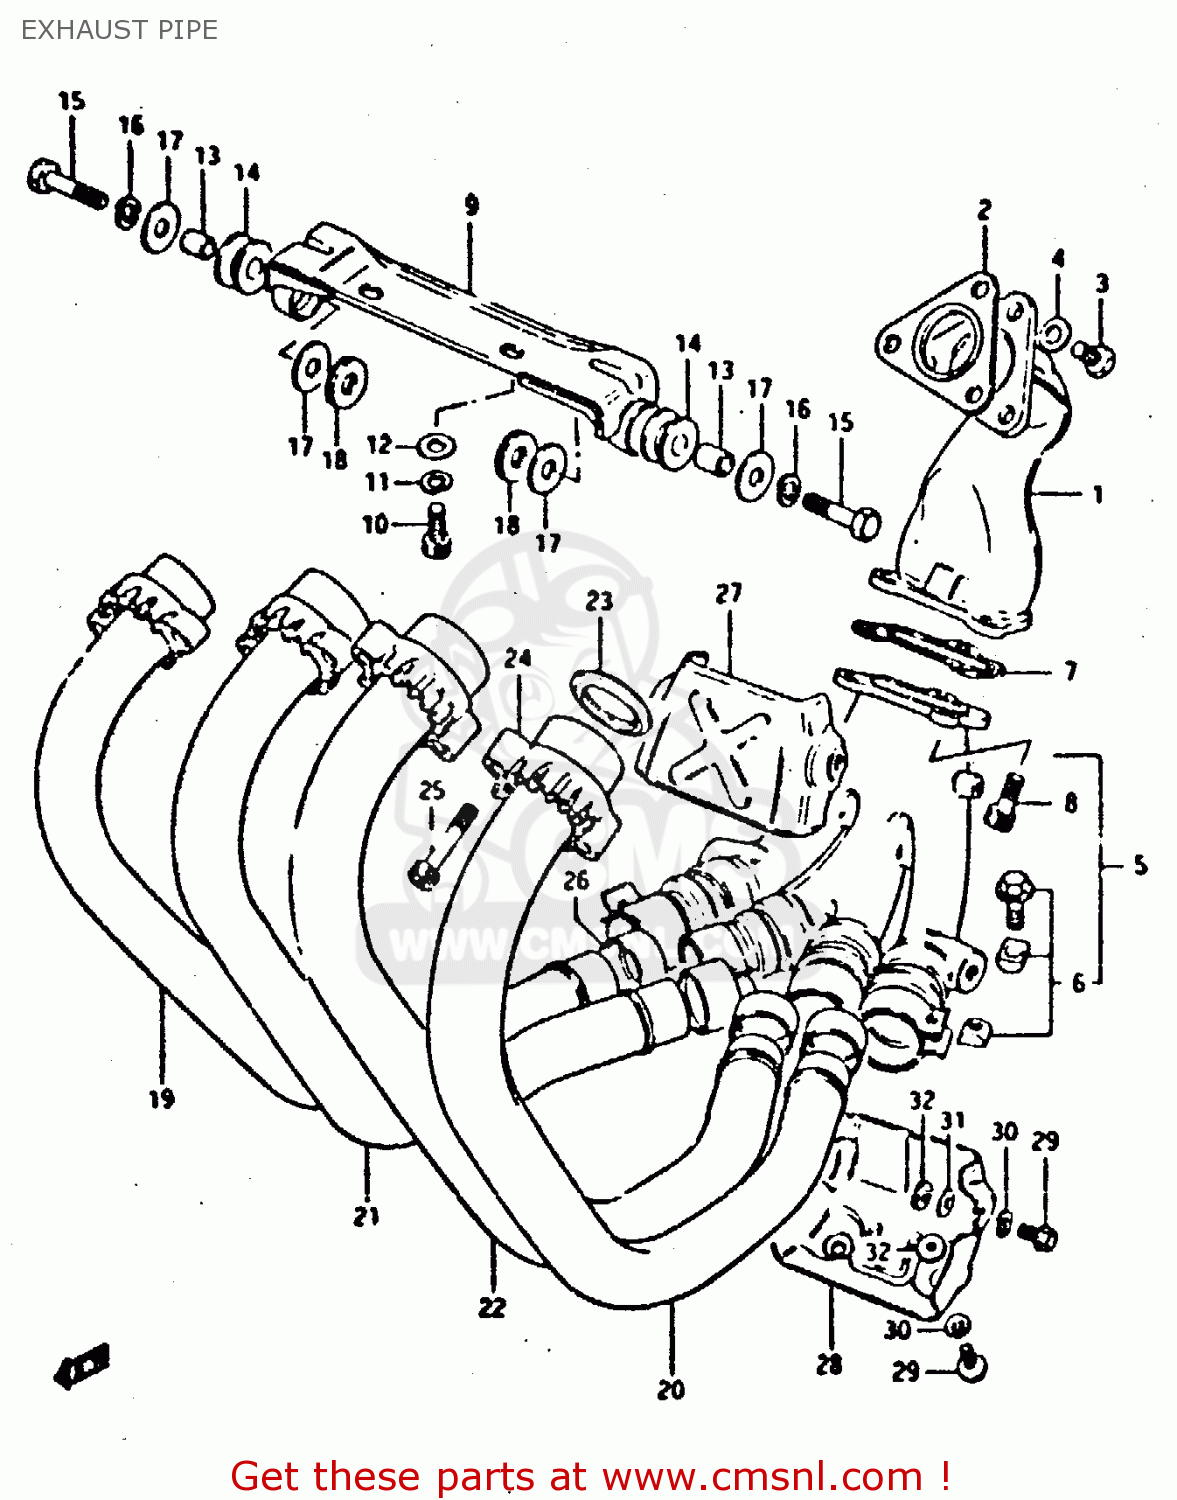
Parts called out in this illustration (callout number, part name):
1	MANIFOLD,TURBO INAKE
2	GASKET (MCA)
3	BOLT
4	WASHER
5	MANIFOLD,EXHAUST
6	BAND SET,EXHAUST PIPE
7	GASKET,EXHAUST (NAS)
8	BOLT(8X20)
9	STAY,MUFFLER SUPPORT
10	BOLT(8X20)
11	LOCK WASHER
12	WASHER,8.5X16X
13	SPACER (8.2X12X17)
14	CUSHION
15	BOLT
16	LOCK WASHER
17	WASHER (8.5X20X1.6)
18	GASKET
19	PIPE,EXHAUST,RIGHT
20	PIPE,EXHAUST,LEFT
21	PIPE,EXHAUST,RIGHT
22	PIPE,EXHAUST,LEFT
23	GASKET,EXHAUST PIPE (NAS)
24	CLAMP,EXHAUST PIPE
25	BOLT
26	CONNECTOR,MUFFLER
27	COVER,MUFFLER
28	COVER, LOWER
29	BOLT
30	LOCK WASHER
31	WASHER
32	GASKET
